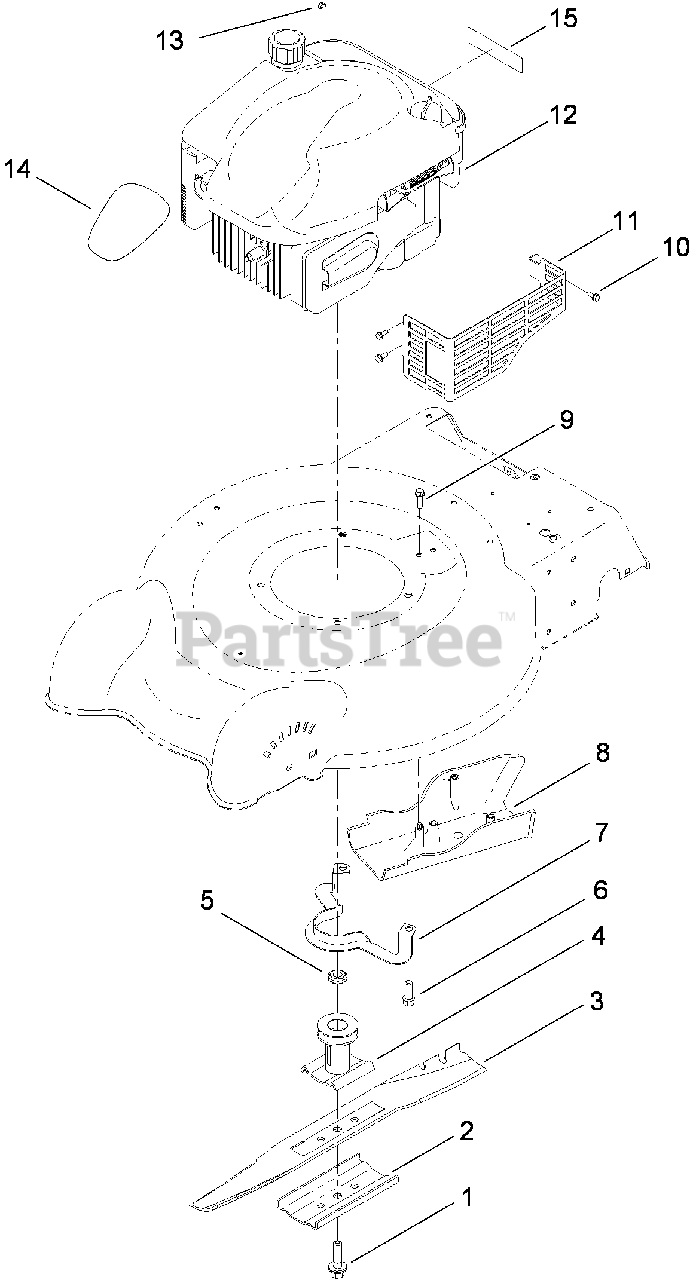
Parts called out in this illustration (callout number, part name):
1	BOLT-BLADE
2	SUPPORT-BLADE
3	BLADE-20 INCH
4	BLADE DRIVER ASM
5	Spacer-Driver
6	SCREW-TAPTITE
8	COVER-BELT
9	SCREW-HWH
10	SCREW-TAPTITE
11	SHIELD-MUFFLER
13	STOP-ROPE
14	DECAL-SHROUD
15	DECAL-ARRESTER, SPARK
